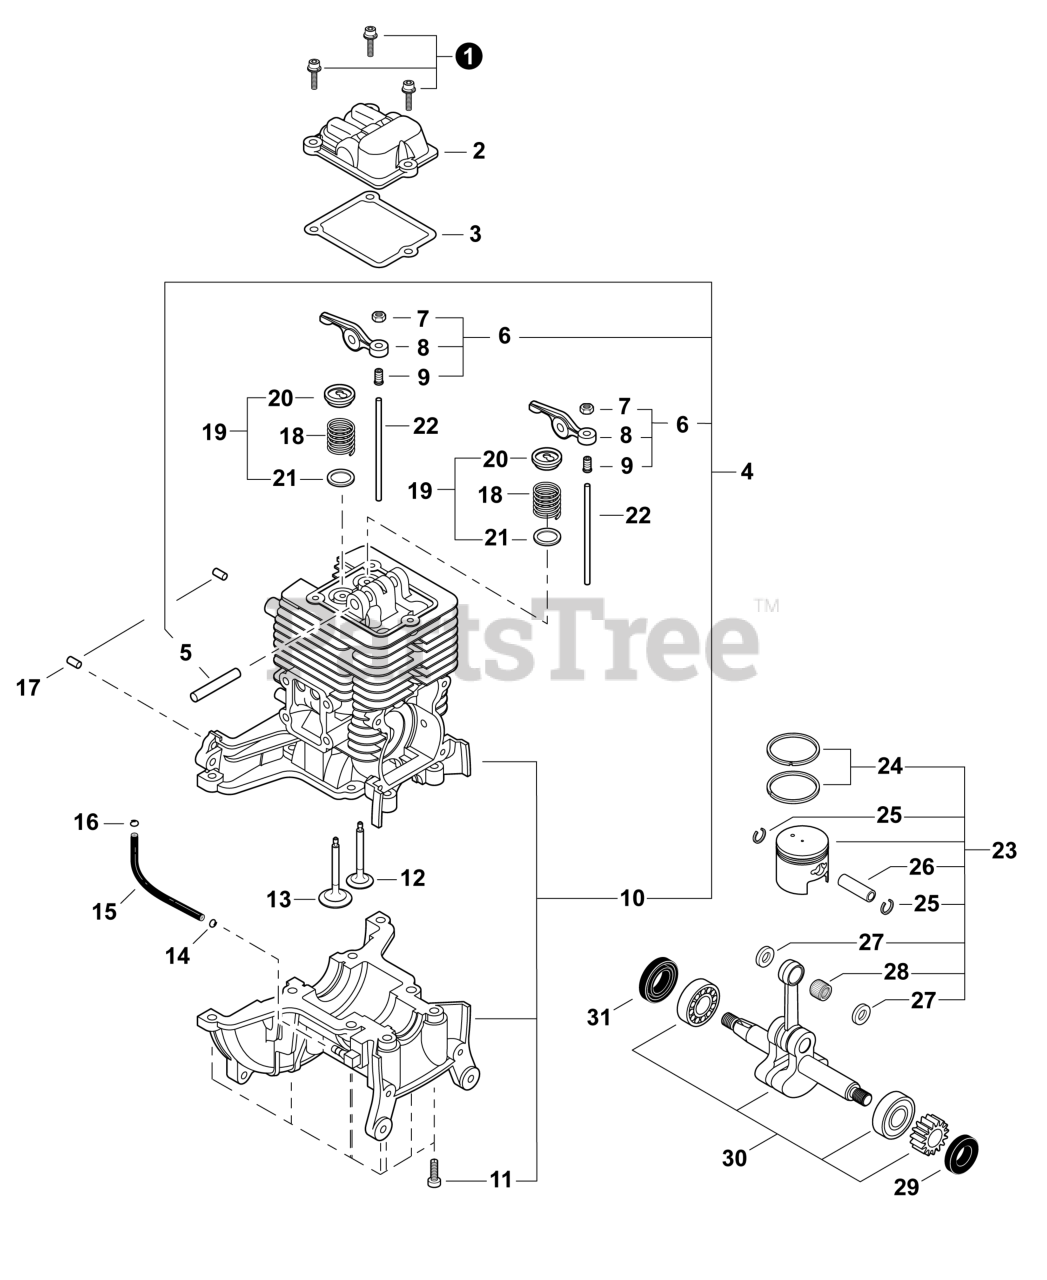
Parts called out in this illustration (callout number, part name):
1	BOLT M4×14
2	COVER, ROCKER ARM
3	GASKET, ROCKER ARM
4	ENGINE BLOCK ASSY
5	SHAFT, ROCKER ARM Ø5×37.8 MM
6	ARM ASSY, ROCKER
7	NUT, ADJUSTER LOCK 5
8	ARM, ROCKER
9	SCREW, ADJUSTER
10	ENGINE BLOCK
11	BOLT 5×16
12	VALVE, EXHAUST
13	VALVE, INTAKE
14	CLIP Ø6
15	PIPE, IMPULSE 3×6×87
17	PIN, LOCATING 4×8
18	SPRING, VALVE
19	RETAINER SET, VALVE
20	RETAINER, VALVE
21	WASHER, VALVE 9
22	PUSHROD
23	PISTON KIT
24	RING, PISTON
25	RING, SNAP
26	PIN, PISTON 10
27	WASHER, THRUST 10
28	BEARING, NEEDLE 10
29	SEAL, OIL 12
30	CRANKSHAFT ASSY
31	SEAL, OIL 12
